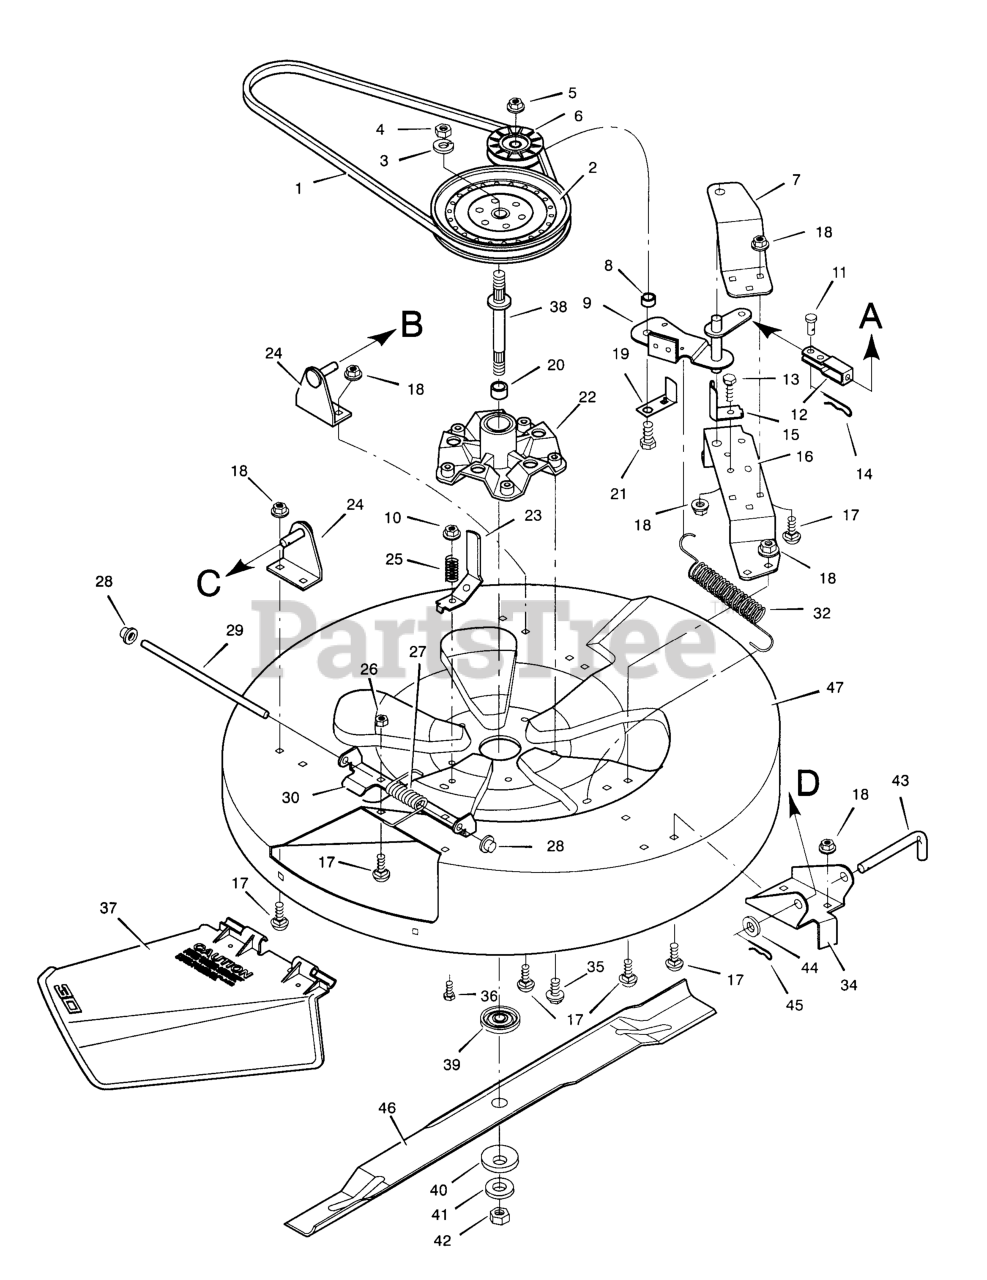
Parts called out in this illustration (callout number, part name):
1	Belt, Mower Drive
2	Pulley, Splined
3	Lockwasher
4	Locknut, Hex
5	Nut, Hex
6	Pulley, Idler
7	Bracket, Upper Idler
9	Assembly, Blade Idler
10	Locknut, Flange
11	Pin, Clevis
13	Bolt, Hex
14	Pin, Hair
15	Guide, Belt
16	Bracket, Lower Idler
17	Bolt, Carriage
18	Nut, Flange
19	Guide, Belt
21	Bolt, Hex
22	Housing, Mandrel
23	Guide, Belt
24	Bracket, Hanger
25	Spring, Compression
26	Nut, Hex
27	Spring - Torsional
28	Push On Cap
30	Hinge, Chute Deflector
32	Spring, Extension
34	Bracket, Front
36	Bolt, Hex
37	Deflector, Chute
38	Mandrel
39	Adapter, Blade
40	Washer, Belleville
41	Washer, Hardened
42	Nut, Hex
43	Pin, Pull
45	Pin, Hair
46	Blade, Standard
